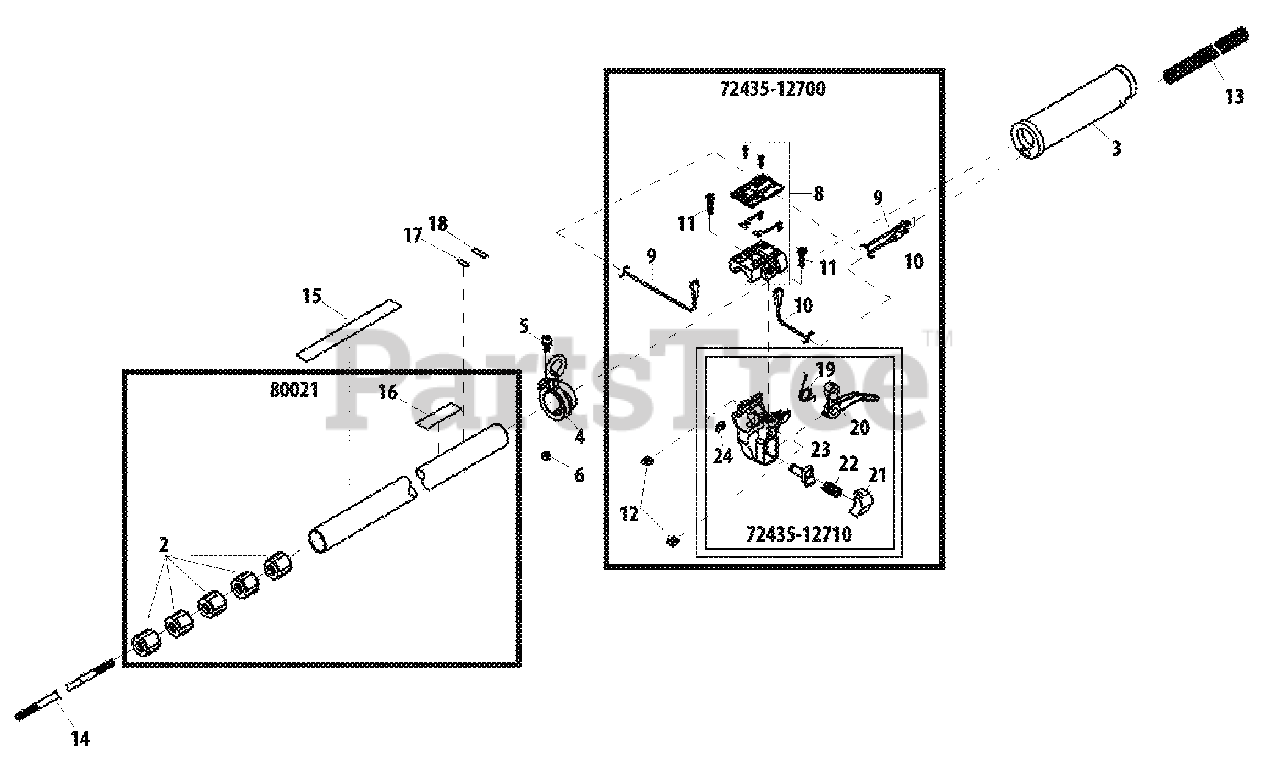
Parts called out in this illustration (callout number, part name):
2	BUSHING
3	GRIP
4	HANGER, SWIVEL
5	BOLT M5×12
6	NUT M5
8	SWITCH ASSY, ON-OFF
9	LEAD - BLACK
10	LEAD - RED
11	BOLT
12	NUT, THROTTLE LEVER
14	MAINSHAFT
15	LABEL - MODEL
16	LABEL, CAUTION (BLADE CAPABLE)
17	LABEL, HANDLE
18	LABEL - ALIGNMENT
19	SPRING, RETURN
20	TRIGGER, THROTTLE
21	BUTTON, THROTTLE LOCK
22	SPRING
24	RING, SNAP
80021	MAIN PIPE ASSY
7243512700	THROTTLE CONTROL ASSY
7243512710	BASE, PURGE
